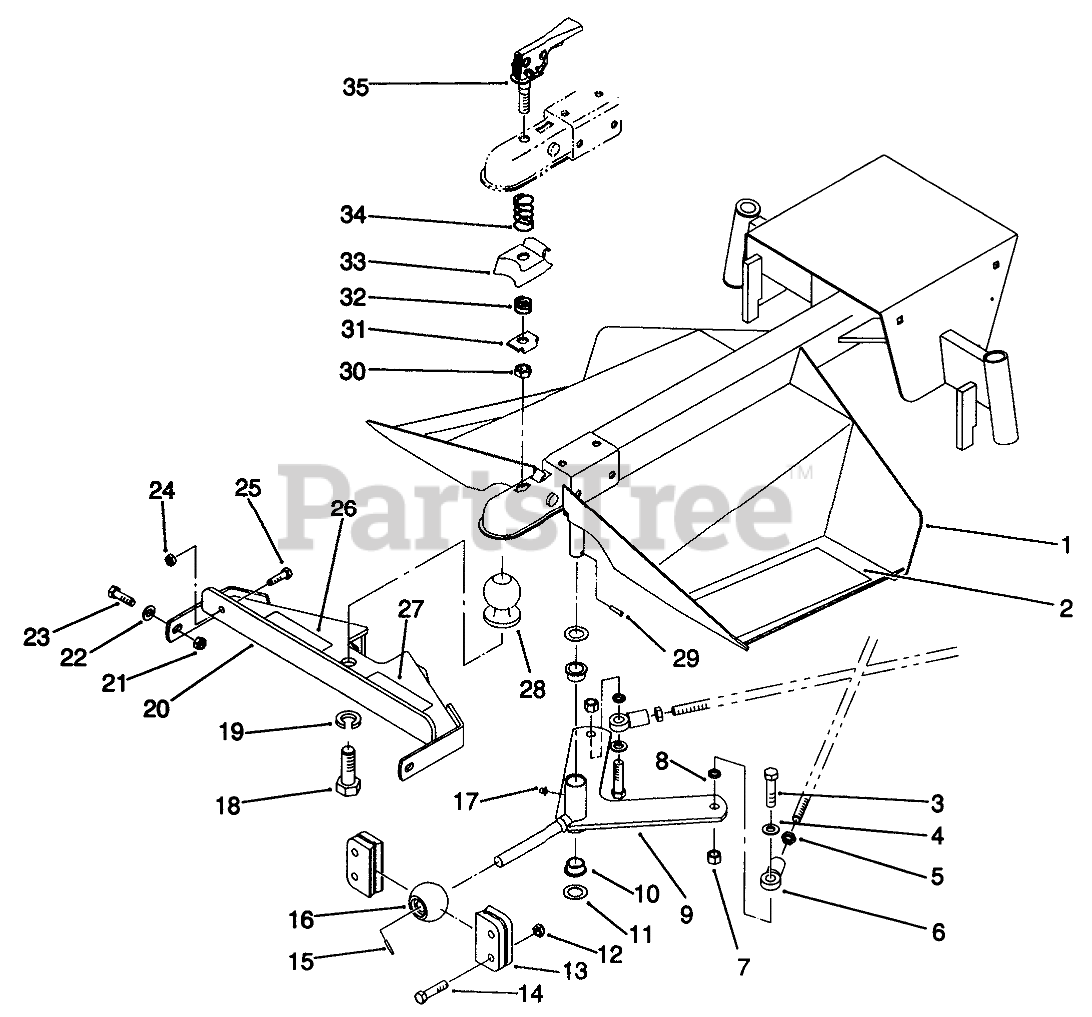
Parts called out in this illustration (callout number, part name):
1	FRAME WA
2	FOOTREST TREAD
3	SCREW-HH
4	WASHER-FLAT
6	BALL JOINT LH
7	NUT-HEX
8	WASHER
9	FRT PIVOT WA/SULKY
10	BEARING-FLANGE
11	WASHER-THRUST
12	NUT-HF
13	CHANNEL
14	SCREW-HHF
15	ROLL PIN
16	SPHERE
17	GREASE FITTING
18	SCREW-HH
19	WASHER-LOCK
20	Plate-Hitch
21	NUT-LOCK, NI
22	WASHER-FLAT
23	SCREW-HH
24	NUT-LOCK, NI
25	SCREW-HH
26	DECAL - CAUTION
27	DECAL - WARNING
28	COUPLER BALL
29	PIN-SPRING
30	Nut-Hex, Jam
31	Plate-Nut, Locking
32	Spring-Lock
33	Clamp-Ball
34	Spring-Release
35	Assembly-Handle (Incl. Ref. #30-34)
